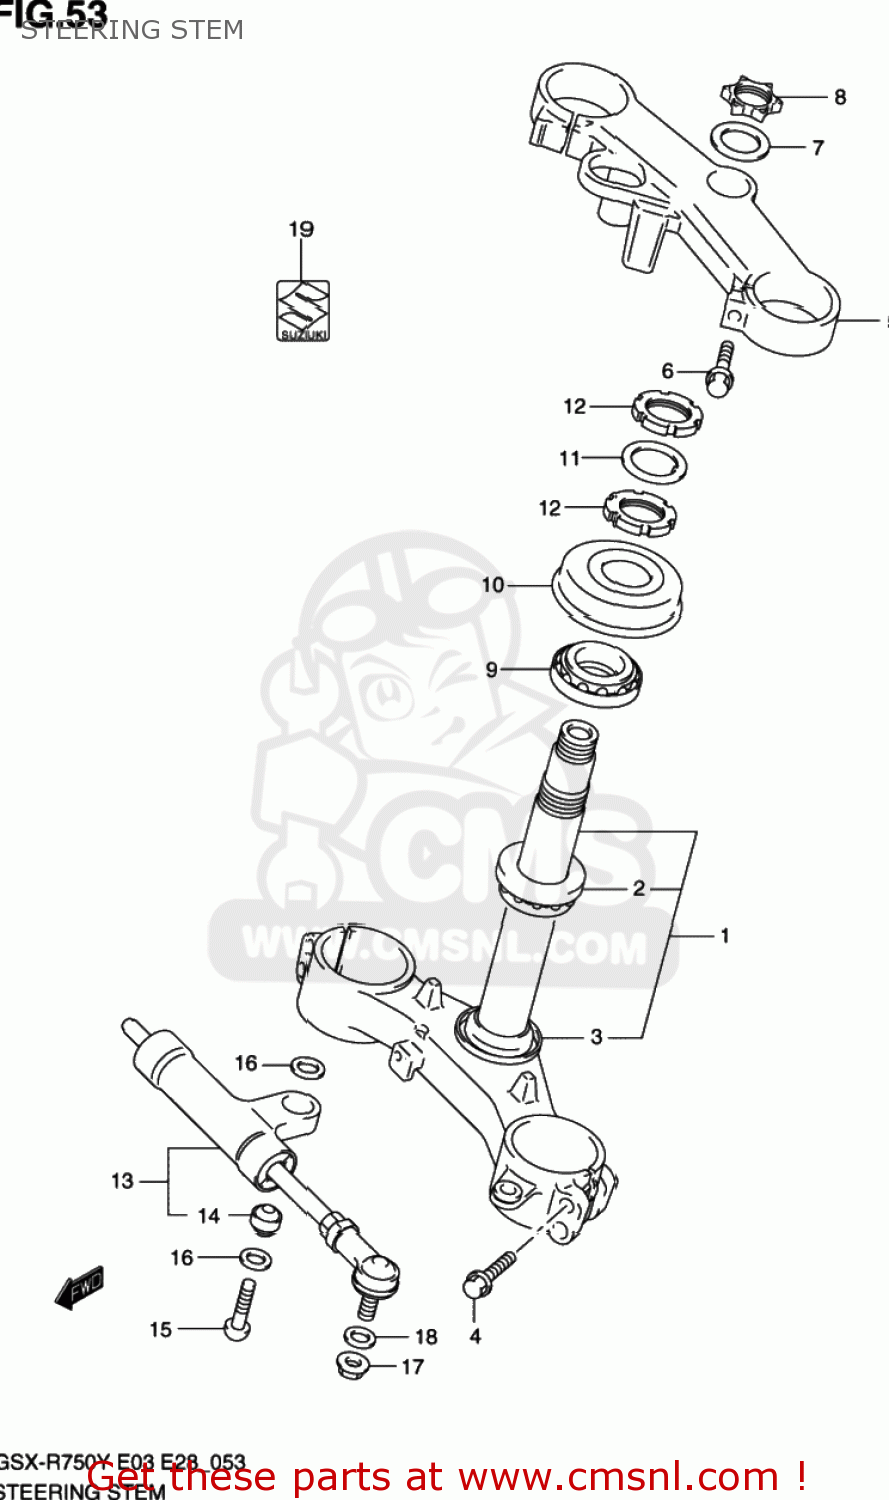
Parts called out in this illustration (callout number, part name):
1	STEM,STEERING
2	BEARING(30X55X17)
3	SEAL,STEERING LWR
4	BOLT
5	HEAD,STEERING STEM
6	BOLT
7	WASHER
8	NUT,STEM HEAD
9	BEARING(30X55X17)
10	SEAL,STEERING UPR DUST
11	WASHER,STEERING STEM
12	NUT,STEERING STEM
13	DAMPER ASSY,STEERING
14	BEARING(8X17.5X11)
15	BOLT(8X35)
16	SEAL,PILLOW BALL,DUST
17	NUT
18	WASHER(8.5X18X1.6)
19	EMBLEM,S
